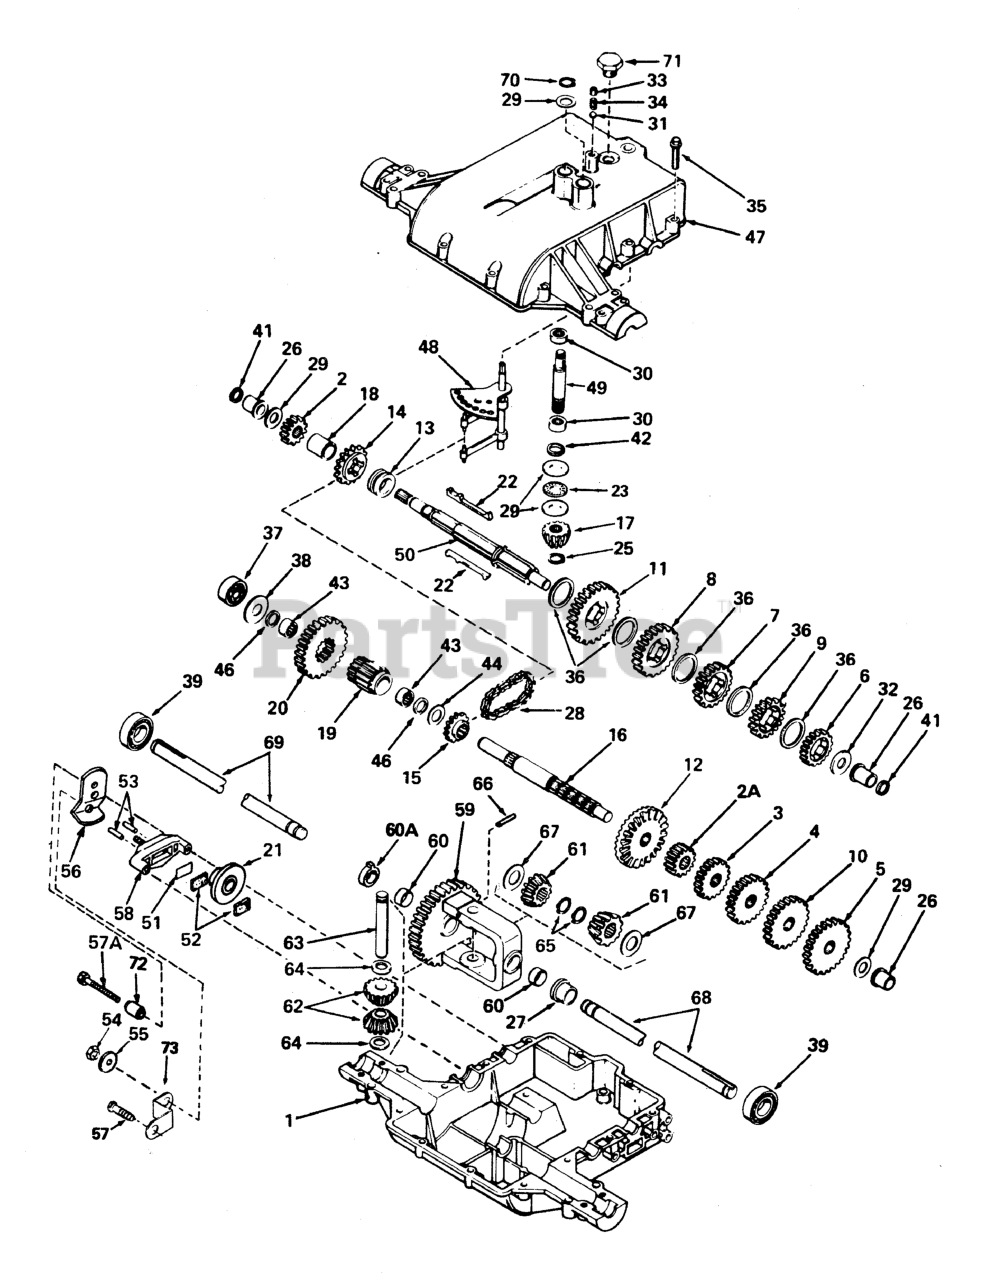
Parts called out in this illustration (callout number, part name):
1	Case, Transaxle
2	Gear, Spur (15 Tooth)
2A	Gear, Spur (12 Tooth)
3	Gear, Spur (15 Tooth)
4	Gear, Spur (20 Tooth)
5	Gear, Spur (28 Tooth)
6	Gear, Spur (22 Tooth)
7	Gear, Spur (30 Tooth)
8	Gear, Spur (35 Tooth)
9	Gear, Spur (25 Tooth)
10	Gear, Spur (25 Tooth)
11	Gear, Spur (37 Tooth)
12	Gear, Bevel (42 Tooth)
13	Collar, Shirt
14	Sprocket (18 Tooth)
15	Sprocket (9 Tooth)
16	Shaft, Counter
17	Bevel Pinion, Input
18	Spacer
19	Pinion, Output
20	Gear, Output
21	Disk, Brake
22	Key
23	Bearing, Thrust
25	Ring, Retaining
26	Bushing, Flanged
27	Bushing, Flanged
28	Chain, Roller (#41, 24 Links)
29	WASHER, Thrust
30	Bearing, Needle
31	Ball, Steel
32	WASHER, Thrust
34	Spring
36	WASHER, Thrust
37	Bearing, Ball
38	WASHER, Flat
39	Bearing, Ball
41	Seal, Square Cut
42	Seal, Square Cut
43	Bearing, Needle
44	WASHER, Flat
46	Ring, Square Cut
47	Cover, Transaxle
48	Rod & Fork Assembly, Shift
49	Shaft, Input
50	Shaft, Brake
51	Plate, Brake Pad
52	Pad, Brake
53	Pin, Dowel
55	WASHER, Flat
56	Lever, Plate
58	Holder, Brake Pad
59	Gear Assembly, Differential
60	Bushing
60A	Bushing
61	Gear, Bevel
62	Pinion, Bevel
63	Pin, Drive
64	WASHER, Thrust
65	Ring, Retaining
66	Pin, Roll
67	WASHER, Thrust
68	Axle (25 - 1/4" Long)
69	Axle (13 - 1/4" Long)
70	Ring, Retaining
71	Plug Hex Head, 9/16-18 Thread
72	Spacer
73	Bracket, Brake Lever
